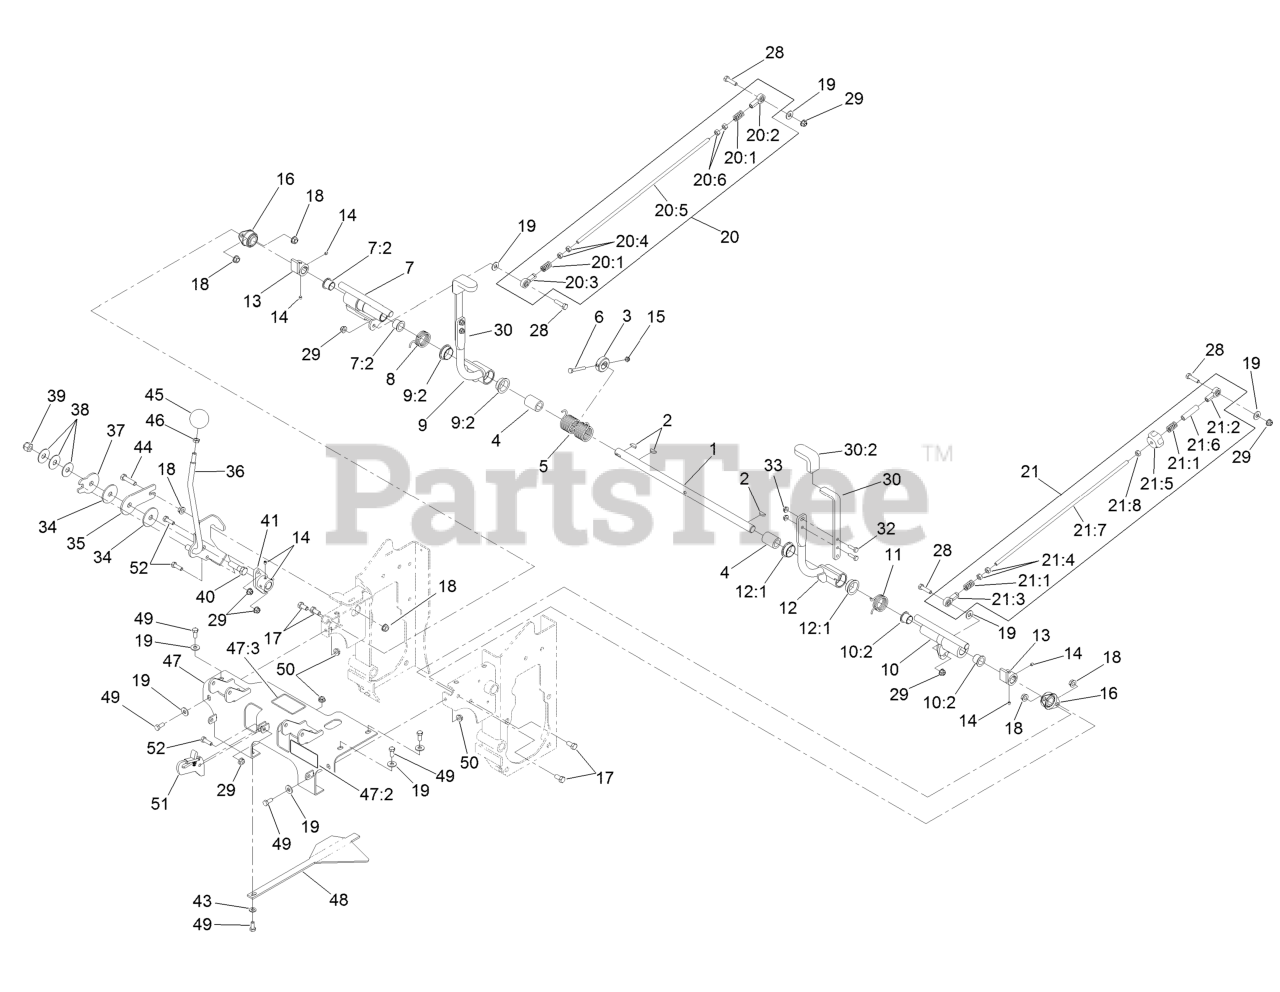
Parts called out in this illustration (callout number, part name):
1	Shaft-Control, Speed
2	Key-Woodruff
3	Stop-Hub, Center
4	Bushing-Plastic
5	Spring-Torsion, Double
6	Screw-HH
7	RH Control Hub ASM
7:2	Bearing-Flange, Iglide
8	Spring-Torsion, RH
9	RH Steering Handle ASM
9:2	Bearing-Flange, Iglide
10	LH Control Hub ASM
10:2	Bearing-Flange, Iglide
11	Spring-Torsion, LH
12	LH Steering Handle ASM
12:1	Bearing-Flange, Iglide
13	Hub-Speed Control
14	Screw-Set
15	Nut-Lock, NI
16	Bearing-Flange, Side
17	Screw-HH
18	Nut-HHF, Whiz
19	Washer-Flat
20	RH Pump Linkage ASM
20:1	Spring-Compression
20:2	Balljoint-RH
20:3	Balljoint-LH
20:5	Rod-Linkage, Steering
20:6	Nut-Hex
21	LH Pump Linkage ASM
21:1	Spring-Compression
21:2	Balljoint-RH
21:3	Balljoint-LH
21:5	Knob-Tracking
21:7	Rod-Linkage, Steering
21:8	Nut-Hex
28	Screw-HH
29	Nut-HF, NI
30	Handle ASM
30:2	Grip-Handle, Steering
32	Screw-HH
34	Disc-Friction
35	Plate-Friction, Speed Control
36	Lever-Speed Control
37	Plate-Friction, Speed Control
38	Washer-Disc, Spring
39	Nut-Hex
40	Screw-HH
41	Hub-Control, Speed
43	Washer-Plain
44	Screw-HH
45	Knob-Ball, Speed Control
46	Nut-Jam
47	Console ASM
47:2	Decal-Danger, Driveline
47:3	Decal-Motor, Wheel
48	Guide-Plenum
49	Screw-HH
52	Screw-HH
